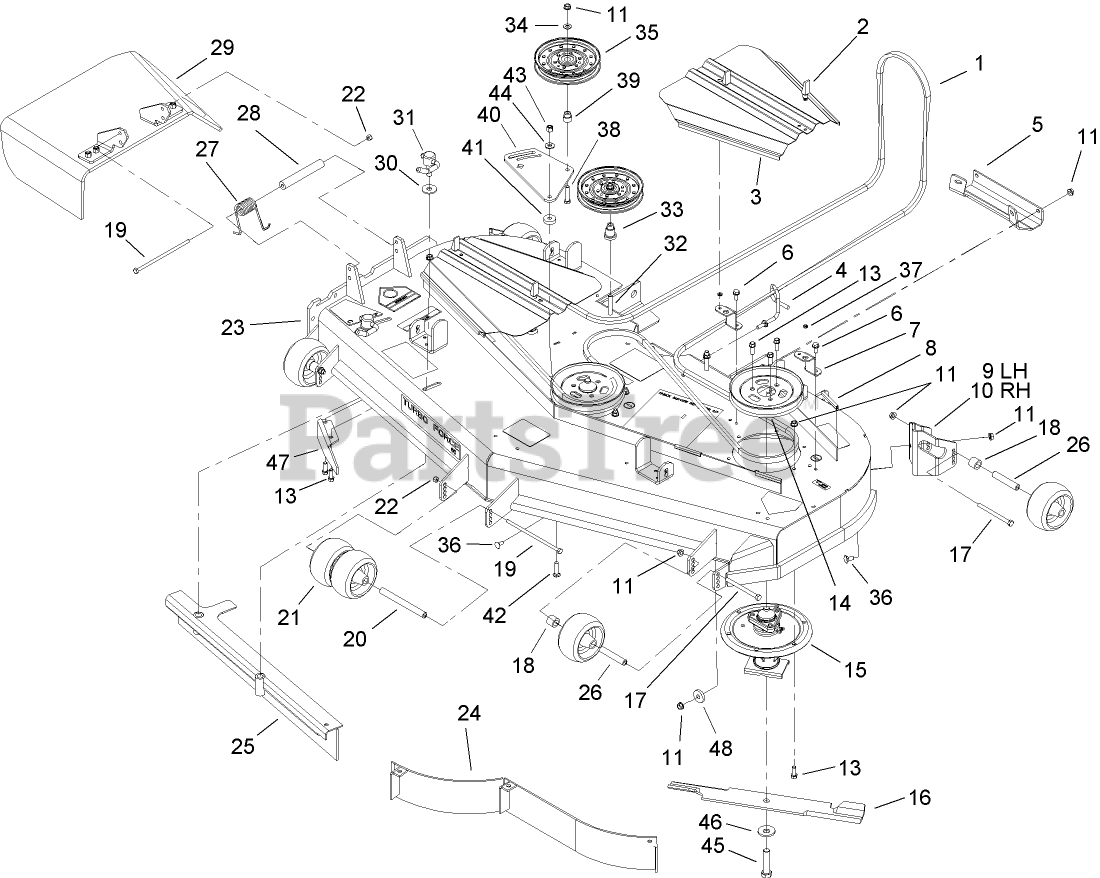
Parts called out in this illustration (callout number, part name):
2	LATCH-SWELL
3	Cover-Belt
4	GUIDE-BELT
5	Plate-Skid
6	SCREW-HWHTF
7	Bracket-Cover
8	STRIP-SEAL
9	MOUNT-WHEEL, LH
10	MOUNT-WHEEL, RH
11	NUT-HHF, WHIZ
13	SCREW-TAPTITE
14	Pulley
15	Spindle ASM
16	Blade-Rotary, High Flow
17	SCREW-HH
18	TUBE-SPACER
19	SCREW-HH
20	SPACER-WHEEL
21	ROLLER-SCALP, ANTI
22	NUT-LOCK, NI
23	Deck Decal ASM
26	TUBE-SPANNER
27	SPRING-TORSION
28	SPACER
29	Rubber Deflector ASM
30	WASHER-PLASTIC
31	Lever ASM
32	SCREW-HH
33	MOUNT-PULLEY
34	WASHER-FLAT
35	Idler-Flat
36	SCREW-CARR
37	WASHER
38	SCREW-HH
39	BUSHING-IDLER
40	Plate-Idler
41	Spacer
42	SCREW-CARR
43	NUT-LOCK, NI
44	WASHER-BELLEVILLE
45	Screw-Cap
46	Washer-Blade Bolt, Heavy
47	BAFFLE-DISCHARGE
48	WASHER
